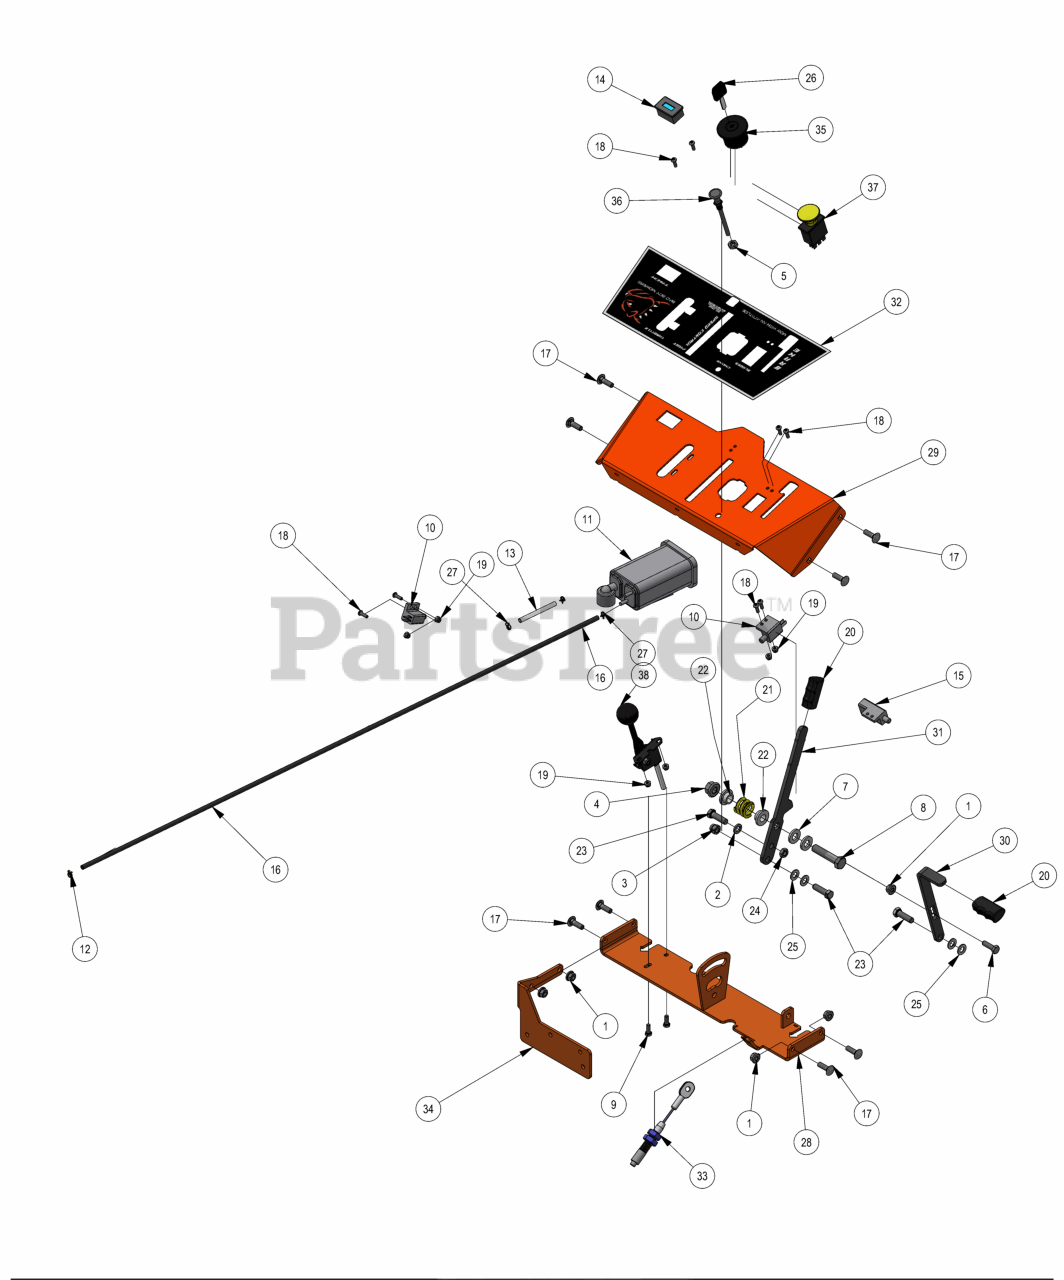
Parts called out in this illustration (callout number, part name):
1	5/16-18 NYLON INSERT FLANGE LOCKNUT ZINC
2	3/8 SPLIT LOCKWASHER ZINC
3	3/8-16 NYLON INSERT LOCKNUT ZINC
4	1/2-13 NYLON INSERT FLANGE LOCKNUT ZINC
5	3/8-24 HEX NUT ZINC YELLOW
6	5/16-18 X 1 HEX CAP SCREW (GR.5) ZINC
7	.505 ID X 1.000 OD X .125 THICK FLAT WASHER NYLON
8	1/2-13 X 2-1/4 HEX CAP SCREW (GR.5) ZINC
9	M6-1.0 X 16MM DIN 933 HEX TAP BOLT (CL 8.8) ZINC
10	safety Switch
11	Carbon Canister for Magnum/MZ
12	3/16" Vinyl Hose Clamp
13	3/16" Clear Vinyl Tubing
14	Tachometer
15	Brake switch 4 prong
16	3/16 Vinyl Tubing, 44"
17	5/16-18 X 1 CARRIAGE BOLT (GR.8) ZINC
18	10-24 X 5/8 BUTTON SOCKET CAP SCREW 18-8 STAINLESS STEEL
19	10-24 NYLON INSERT LOCKNUT ZINC
20	Rubber Brake Grip-cZT/ZT 2013
21	Drive Lever Spring
22	.525 ID SHOULDER WASHER NYLON
23	3/8-16 X 1-1/4 HEX CAP SCREW (GR.5) ZINC
24	3/8-16 HEX JAM 2-WAY REVERSIBLE CENTER LOCKNUT ZINC
25	.390 ID X .750 OD X .062 THK FLAT WASHER NYLON
26	Ignition Key
27	8.6mm Hose Clamp
28	2020 Walk Cross Support Weldment
29	2020 Walk Control Panel
30	Walk Brake Handle
31	Walk Behind Speed Control Lever
32	2020 Walkbehind Control Panel Decal
33	Brake Cable
34	2022 Walk Behind Relay Mount Plate - Painted
35	Ignition Switch
37	PTO Switch
38	Throttle Lever Assembly
